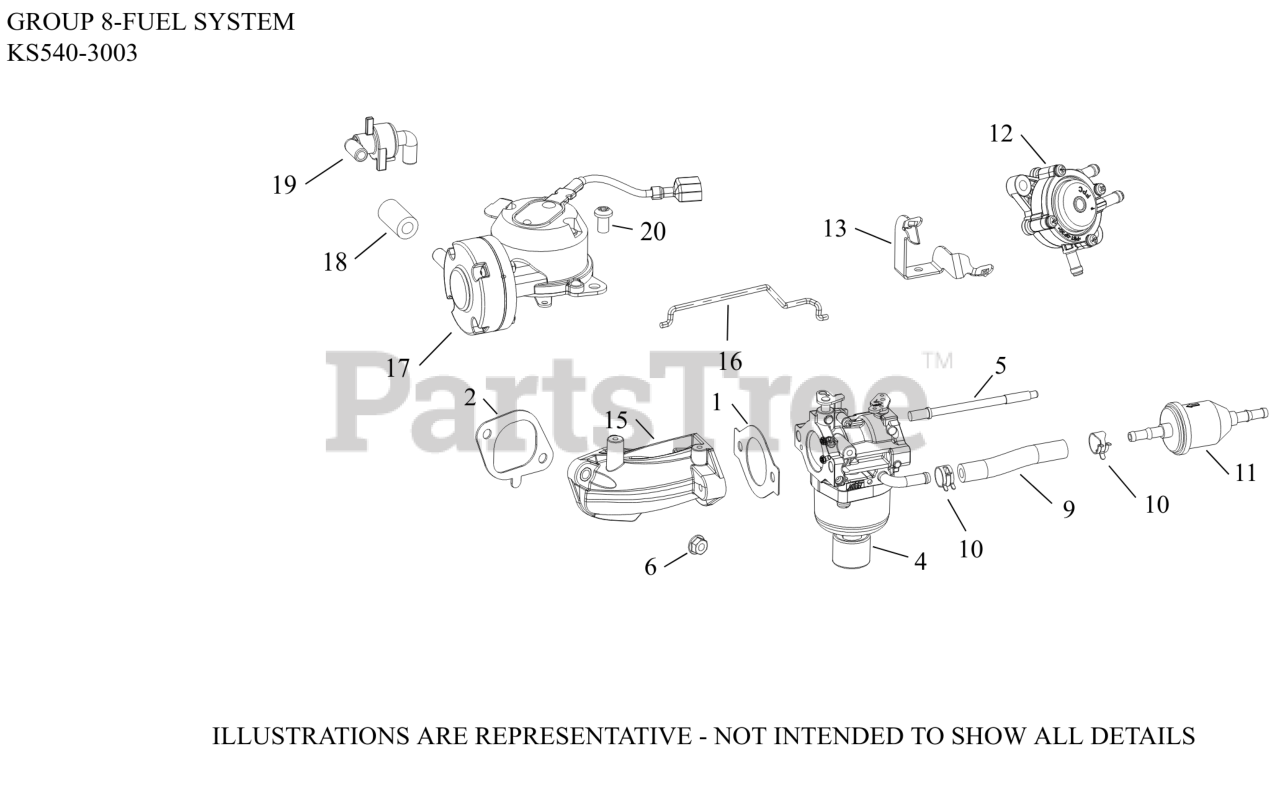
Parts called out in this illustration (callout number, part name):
1	GASKET, CARBURETOR (THROTTLE)
2	GASKET, INTAKE MANIFOLD
4	KIT,CARB(NIKKI)
5	STUD, CARBURETOR
6	NUT, FLG M6X1.0
9	HOSE,LW PERM.FUEL 24.00"-USE 25 111 81-S
10	SPRING CLAMP, HOSE
11	FILTER,FUEL 51 MICRON (FUEL PUMP)
12	PUMP, FUEL (PULSE)-(#2539326S)
13	BRACKET, FUEL PUMP
15	MANIFOLD, INTAKE ASSY
16	LINKAGE, CHOKE
17	DIAPHRAGM ASSY
18	HOSE, VACUUM
19	CHECK VALVE ASSY
20	SCREW, K40 X 1.79 TFS
NI	HIGH ALTITUDE KIT (5000 FT)
NI	KIT, OVERHAUL
NI	KIT, CHOKE SHAFT
NI	KIT, O-RING
NI	KIT, SOLENOID (NIKKI)
NI	KIT, BOWL WITH O-RINGS
NI	KIT, FLOAT & INLET NEEDLE FOR FUEL PUMP
NI	KIT, THROTTLE SHAFT
